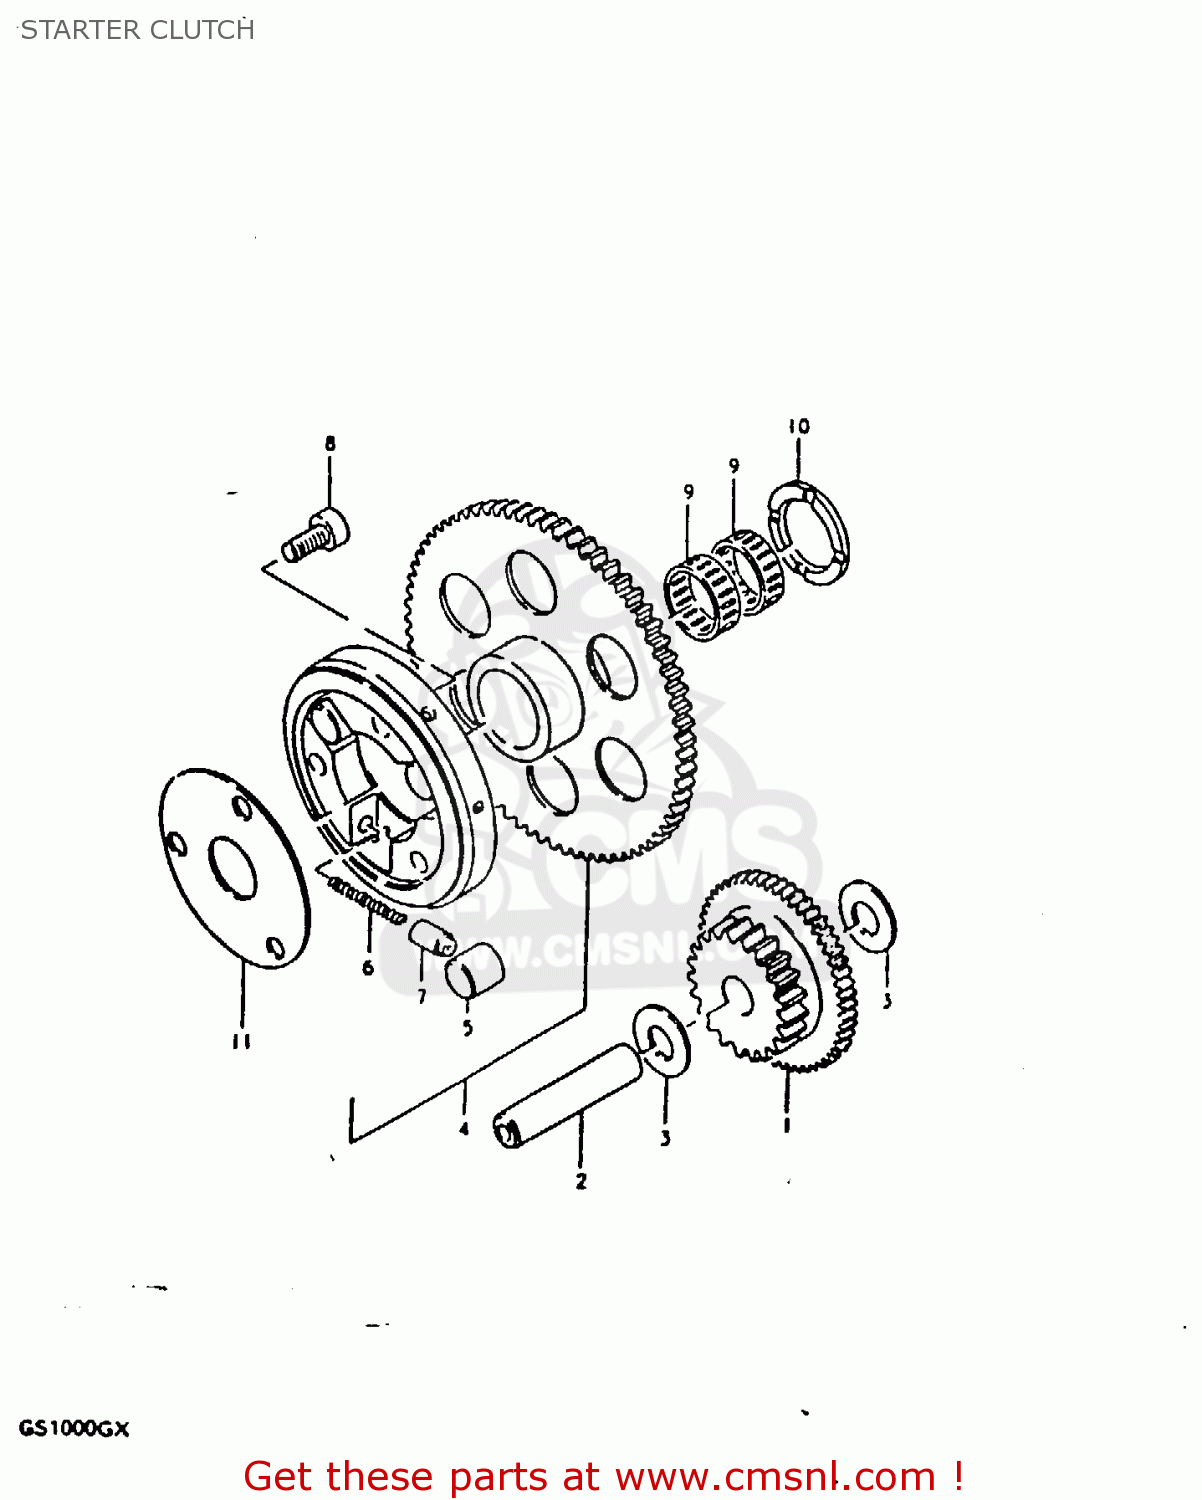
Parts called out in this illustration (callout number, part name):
1	GEAR,STARTER IDLE
2	PIN(7.4X13X56)
3	WASHER(13.3X25X0.85)
4	CLUTCH SET,STARTER
5	PIN(14X13)
6	SPRING
7	PIECE,PUSH
8	BOLT
9	ROLLER BEARING (25X30X9
10	WASHER(25X38X2.5)
11	SHIM,STARTER CLUTCH HUB
